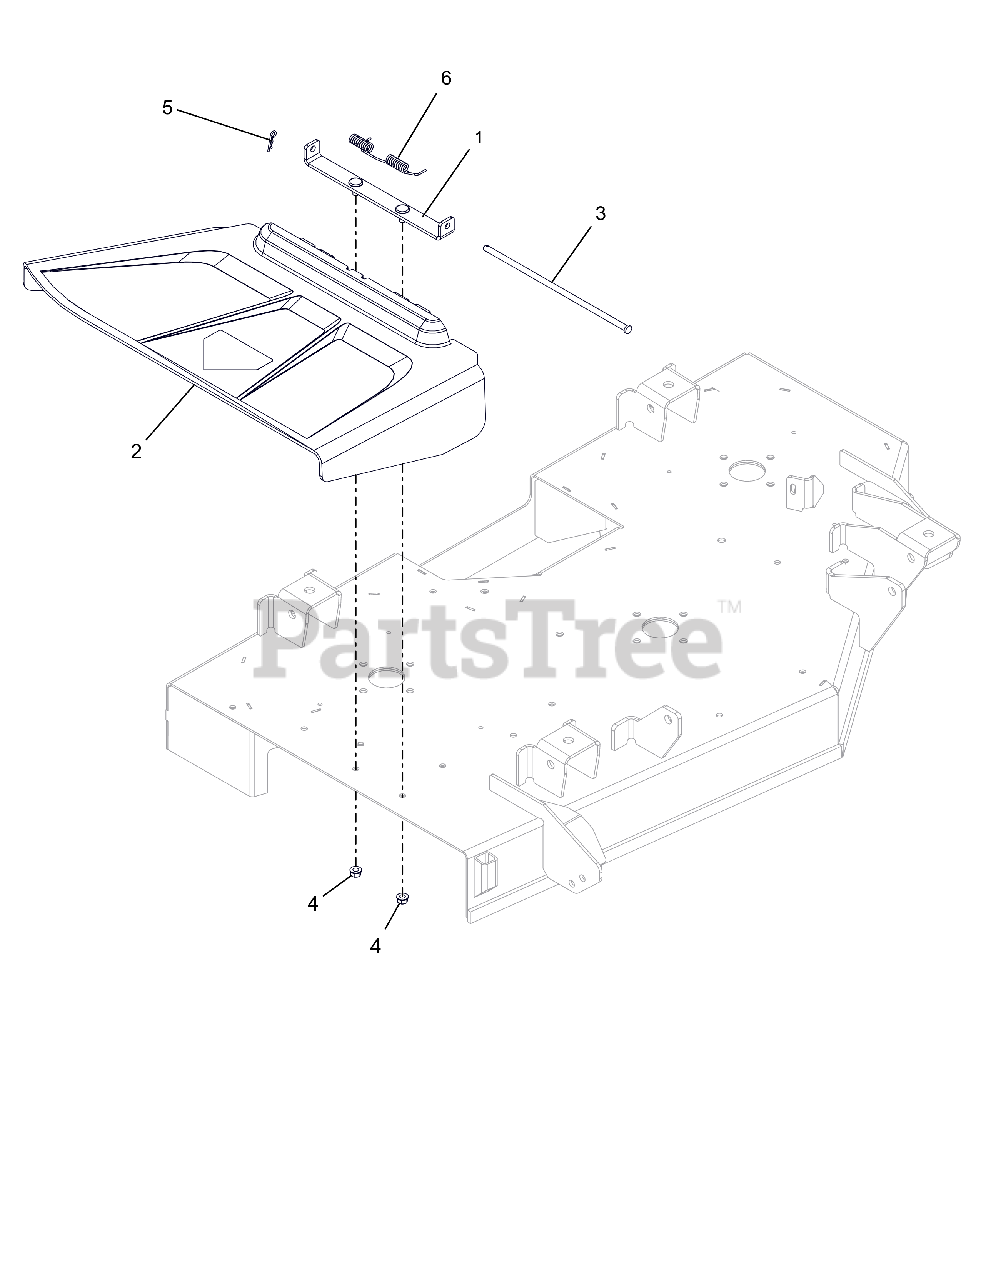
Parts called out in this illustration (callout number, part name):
1	WLDMT, CHUTE MT BRKT
2	CHUTE, SIDE DISCHARGE
3	PIN, 5/16 X 10.5
4	NUT-LK-TOP-FLG .312-18 GF ZCC
5	PIN, HAIR #213 .08X1.19 ZCC
6	SPRING-TORSION
